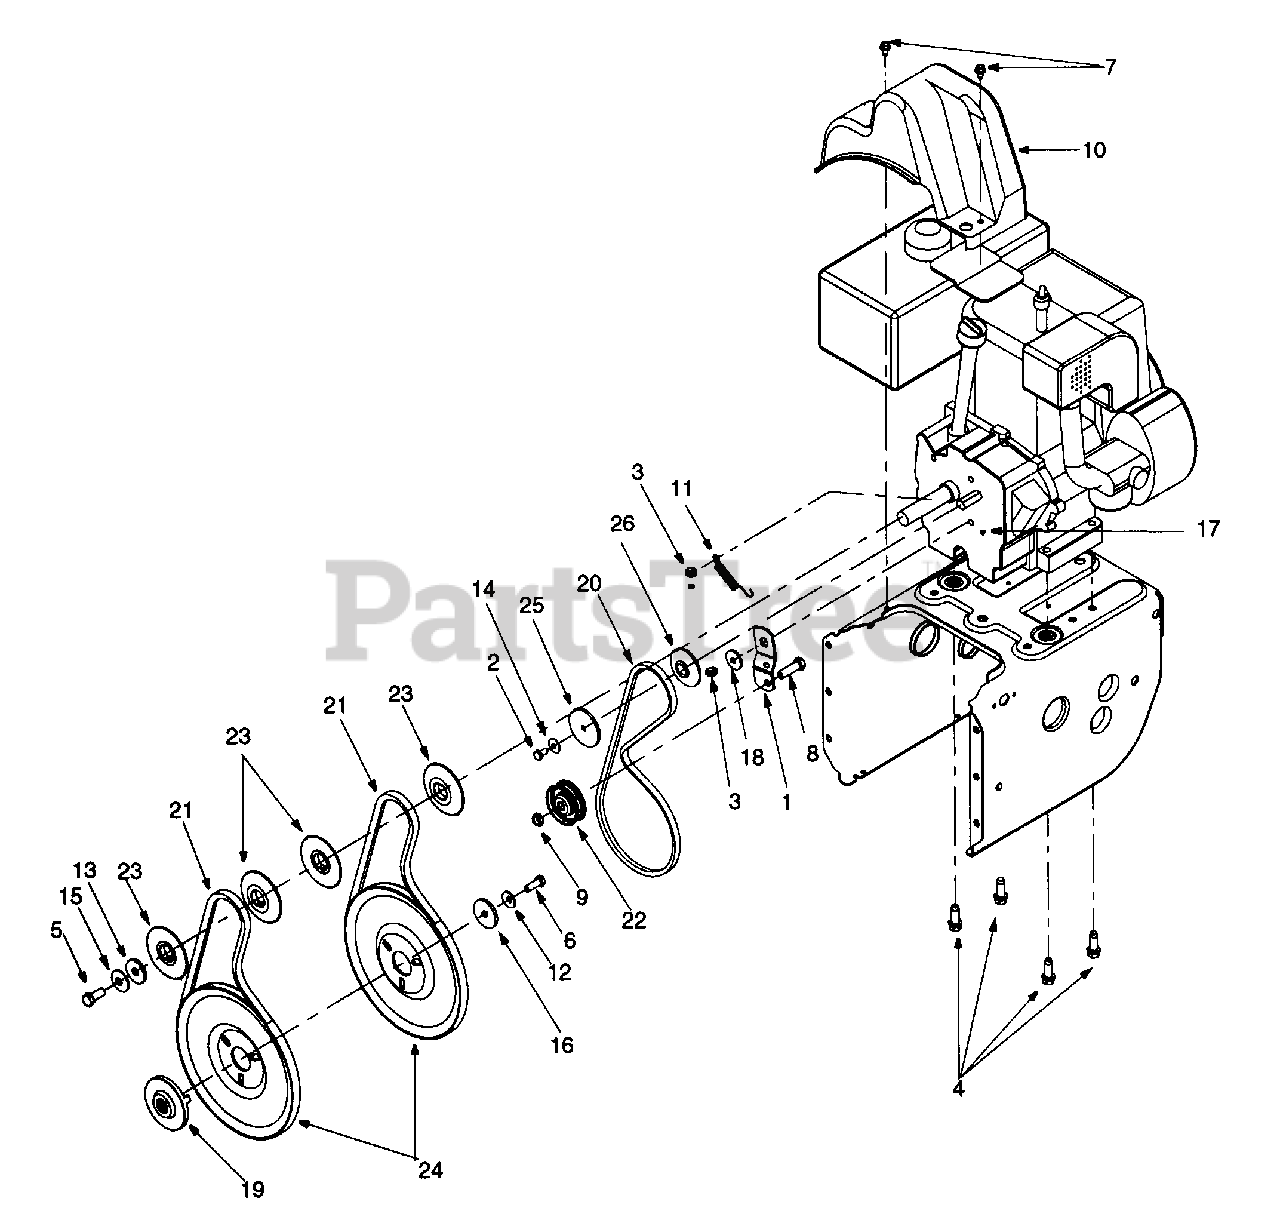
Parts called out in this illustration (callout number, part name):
3	Hex Screw w/ Patch: 5/16-24 x 0.75"
4	Hex Washer Head TT Sems Screw
5	Hex Bolt 3/8-24 x .875" Gr.8
6	Hex Screw w/ Patch: 5/16-24 x .875" Gr 5
7	Hex Washer Head TT
8	Hex Screw: 3/8-16 x 1.0"
9	Top Lock Jam Nut: 3/8-16
10	Belt Cover
11	Extension Spring
12	Bellevile Washer
13	Flat Washer
14	Bell Washer
15	Bell Washer
16	Flat Washer
17	Grease
18	Shoulder Spacer
19	Adapter Pulley
20	V-Belt
21	Belt
22	Flat Idler
23	Pulley Half
24	Auger Pulley
25	Pulley Half
26	Pulley Half
